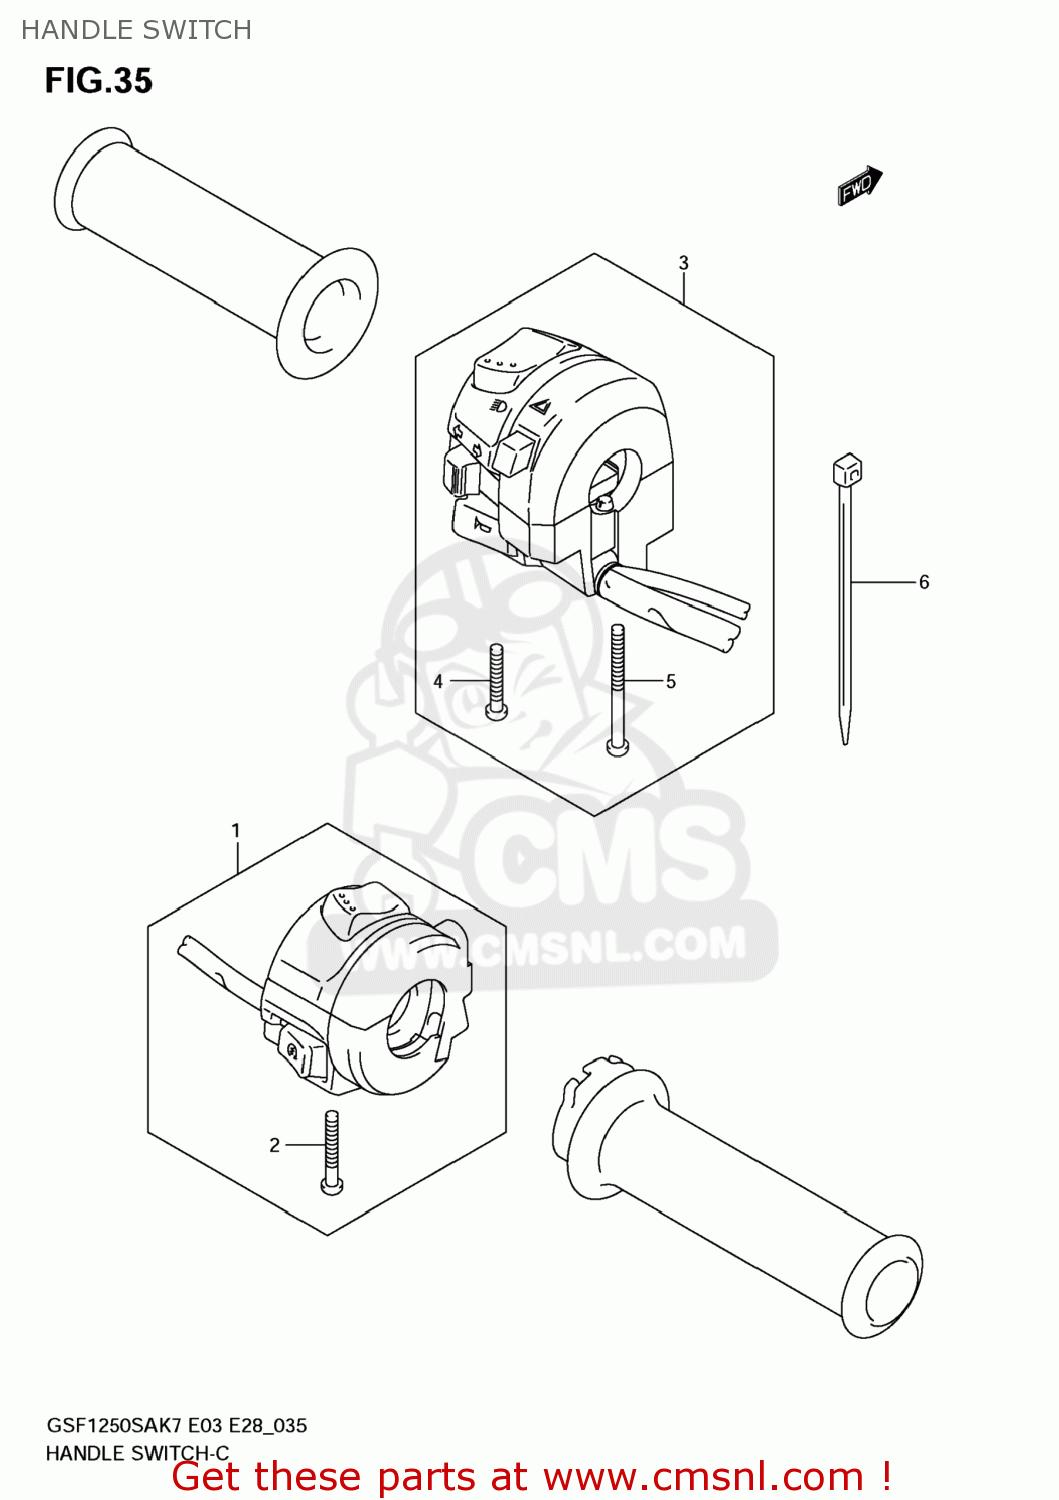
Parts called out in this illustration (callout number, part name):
1	SWITCH ASSY,HANDLE,R
2	SCREW
3	SWITCH ASSY,HA
4	SCREW
5	SCREW
6	CLAMP(L:145)
